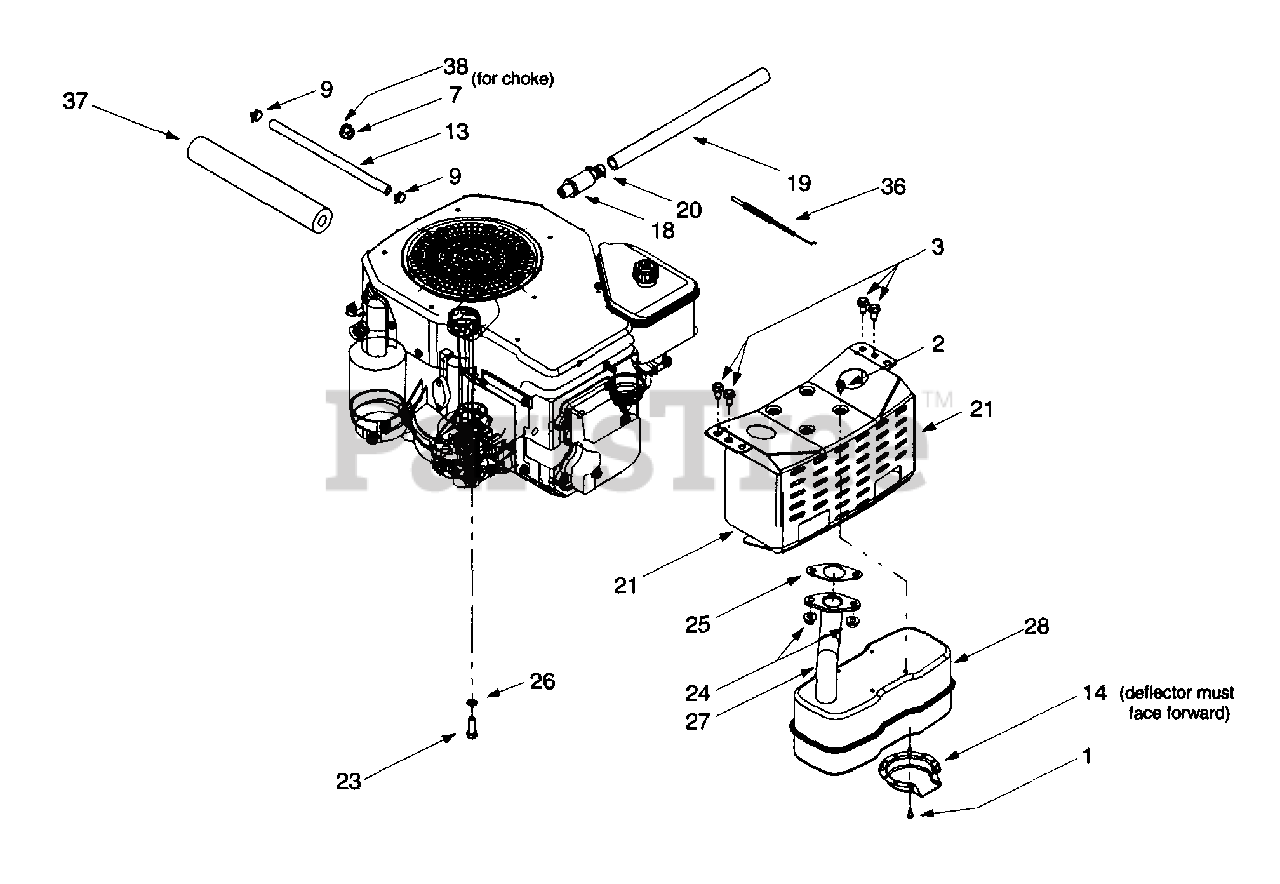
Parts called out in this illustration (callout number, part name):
1	Self-tapping Screw, #8-32 x .375
2	Self-tapping Screw, 1/4-20 x .5
3	Self-tapping Screw, 5/16-18 x .625
7	Hex Nut, 3/8-16
9	Hose Clamp
13	Fuel Line Hose
14	Muffler Deflector
18	Oil Drain Valve
19	Oil Drain Hose
20	Oil Drain Cap
23	Hex Cap Screw, M8-1.25 x 25
24	Flange Nut, M8-1.25
25	Exhaust Gasket
26	External Lock Washer, 5/16
27	Exhaust Pipe
28	Muffler, Single Inlet
36	Throttle Cable
37	Foam
38	Flat Washer, .406 x .875 x .059
